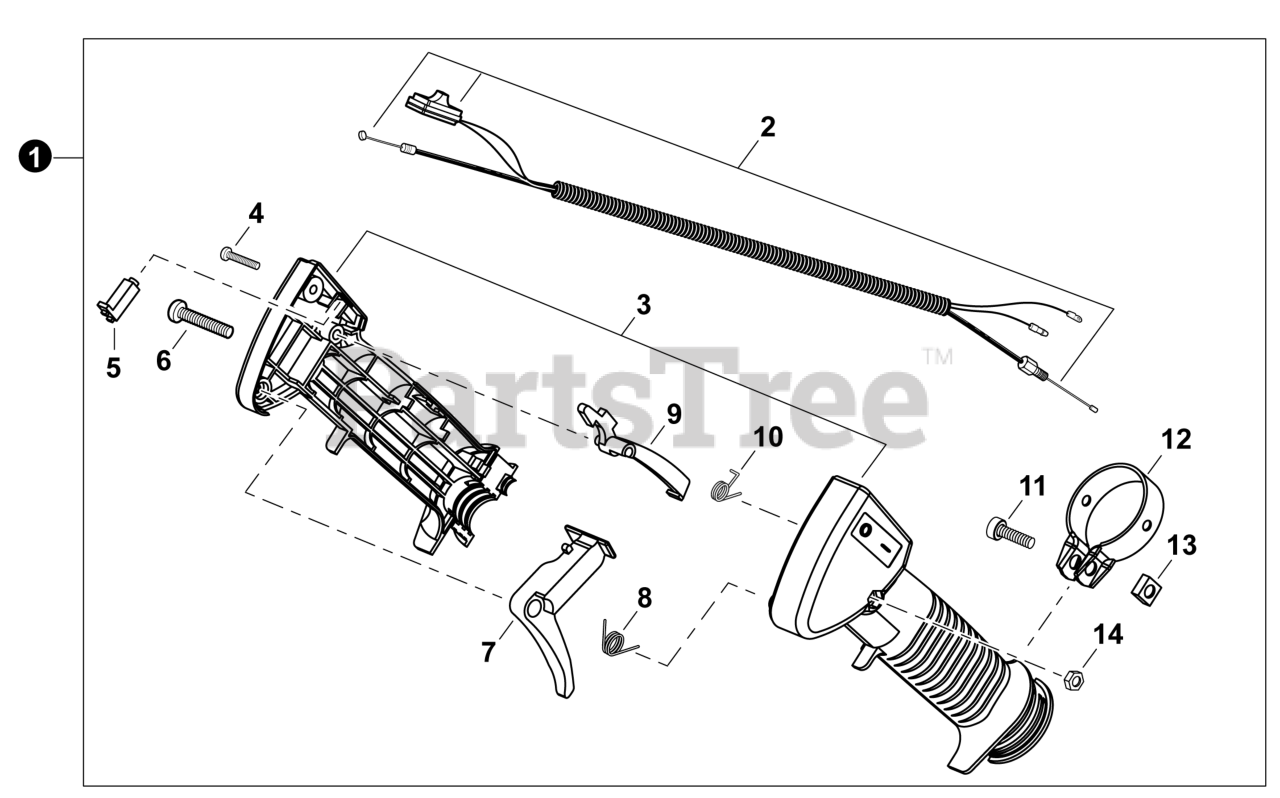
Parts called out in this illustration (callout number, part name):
1	THROTTLE CONTROL ASSY
2	CABLE ASSY, CONTROL
3	GRIP BODY SET
4	SCREW, TAPPING
6	SCREW M5×35
7	TRIGGER, THROTTLE
8	SPRING, RETURN
9	LOCKOUT, THROTTLE
11	BOLT 6×20
